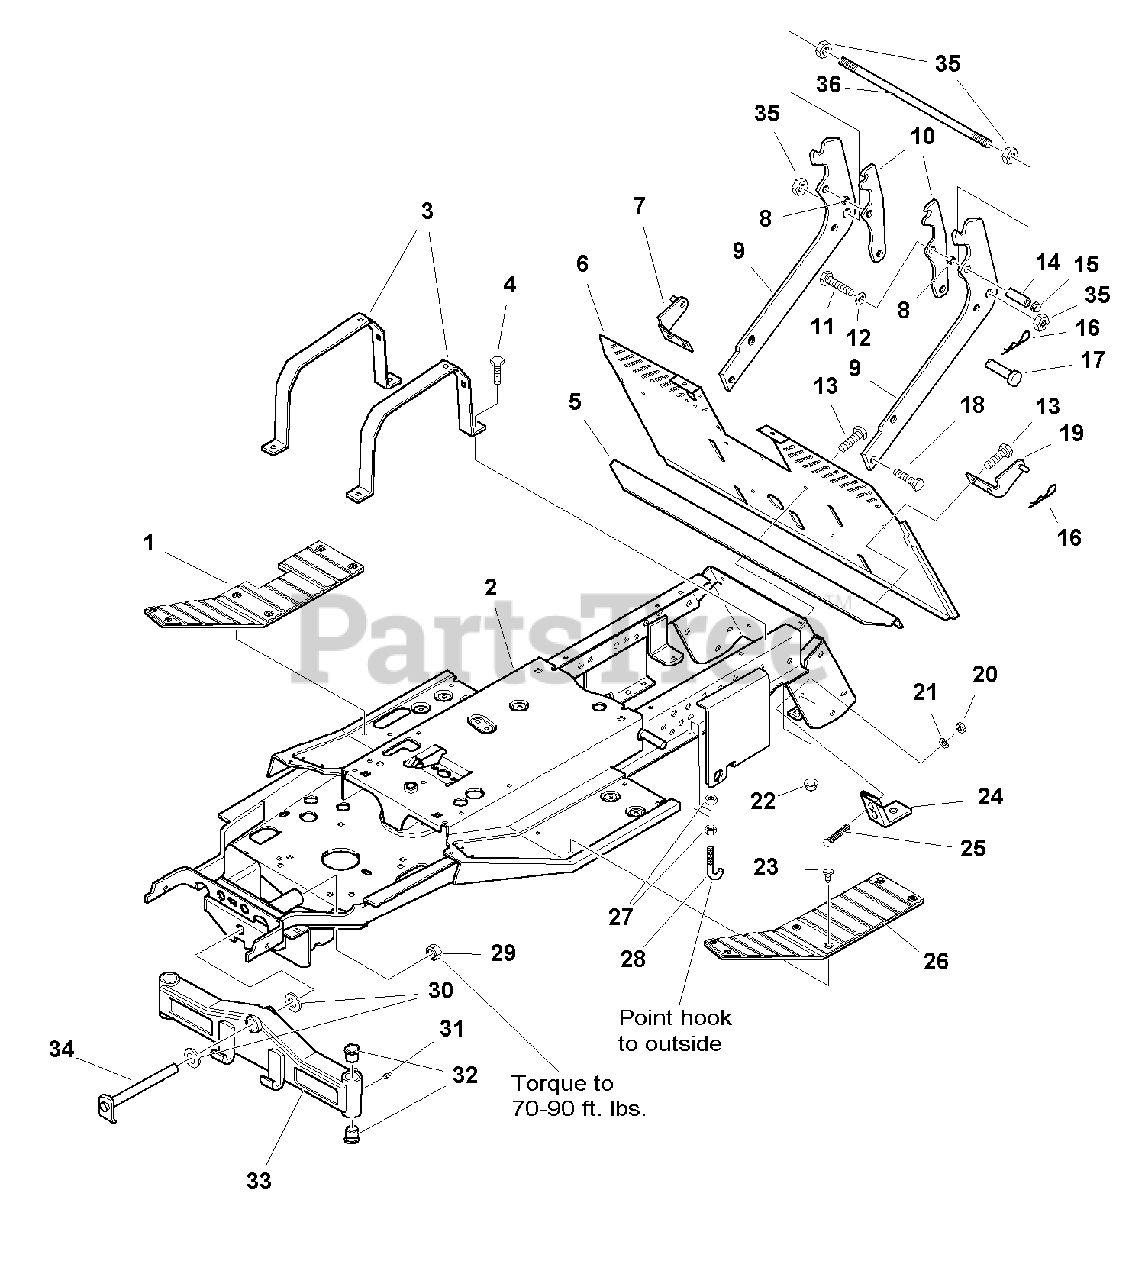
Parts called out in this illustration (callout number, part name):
1	PAD, Footrest, R H
2	FRAME ASSEMBLY
3	STRAP, Fuel Tank
4	CAPSCREW, Hex Washer Head, Taptite, 5/16-18 x 1
5	SUPPORT, Brace
6	BACKPLATE, Grass Bag
7	BRACKET & PIVOT ASSEMBLY, R H Cylinder
9	SUPPORT, Hopper
10	LATCH, Support
11	CAPSCREW, Hex Head, 5/16-18 x 3
12	WASHER, Flat, 5/16
13	CAPSCREW, Hex Washer Head, Taptite, 5/16-18 x 3/4
15	NUT, Hex Flange Whizlock, 5/16-18
16	CLIP, Hair Pin
17	PIN, Round Head Drilled, 3/8 X 1
18	CAPSCREW, Hex Flange Whizlock, 7/16-14 x 1
19	BRACKET & PIVOT ASSEMBLY, L H Cylinder
20	NUT, Hex, 3/8-16
21	LOCKWASHER, Spring, 3/8
22	NUT, Hex Flange Whizlock, 7/16-14
23	FASTENER, Panel
24	DRAWBAR
25	CARRIAGE BOLT, 3/8-16 x 1
26	PAD, Footrest, L H
27	NUT, Hex Flange 5/16-18
29	NUT, Hex Full Lock, 3/4-16
30	WASHER, Special, 7/8 x 1-3/4 x 1/16
31	FITTING, Grease
32	BUSHING, Nylon
33	AXLE ASSEMBLY, Front
34	SHAFT & LOCK ASSEMBLY, Axle Pivot
35	NUT, Hex 1/2-13
36	ROD, Support
